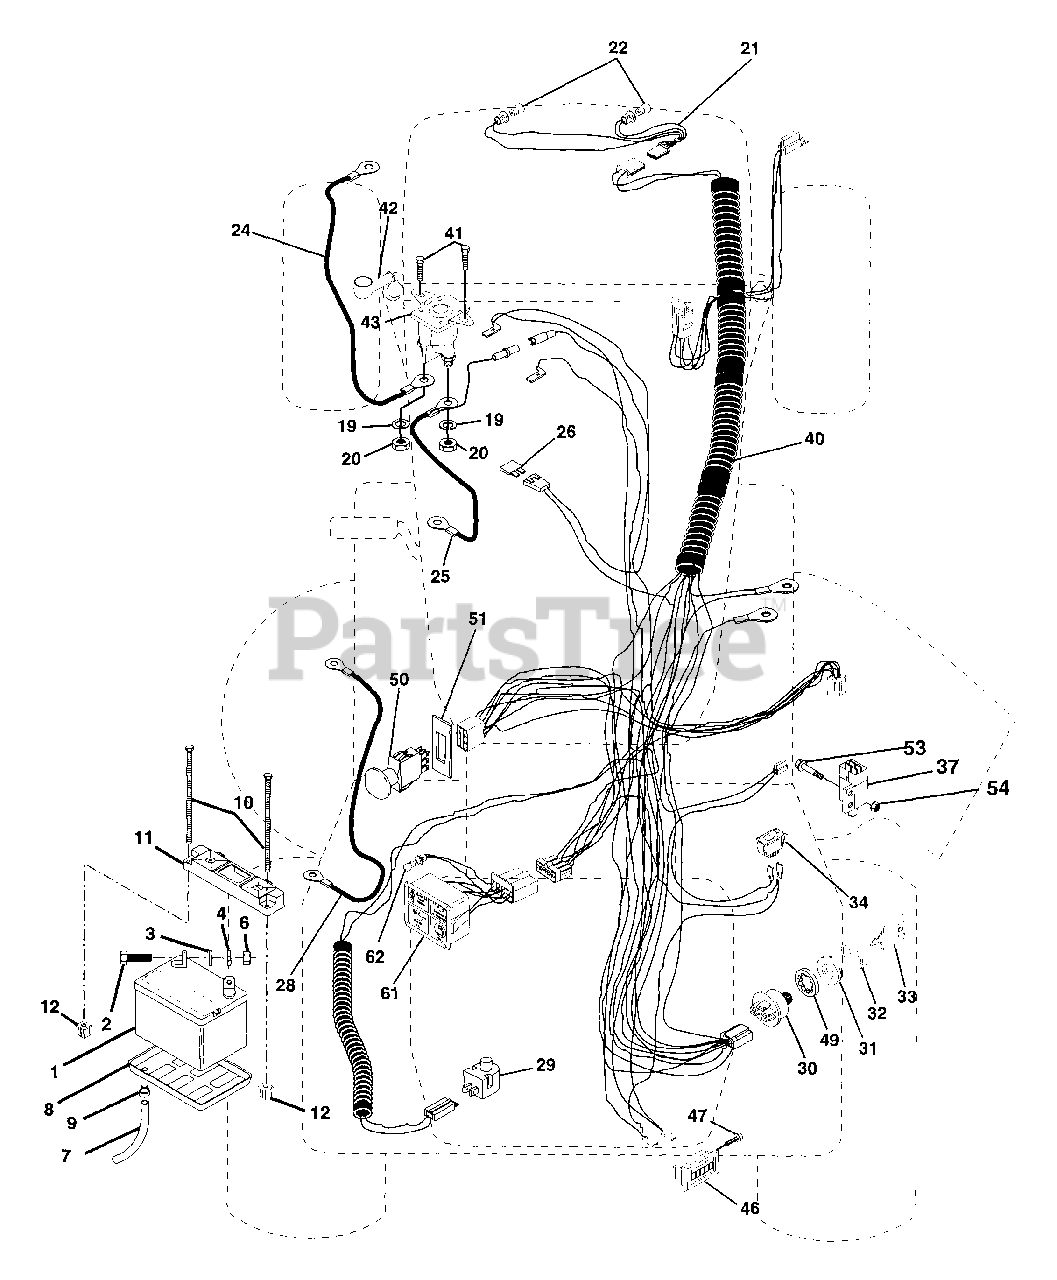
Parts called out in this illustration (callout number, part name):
1	Battery
2	Bolt Hex Head 1/4-20 x 3/4
3	Washer, Lock 1/4
4	Washer 9/32 x 5/8 x 16 Ga
6	Nut Fin Hex 1/4-20
7	Tube, Plastic
8	Tray, Battery
9	Clamp, Hose
10	Bolt, Battery Frt. 1/4-20 x 7-1/2 Zinc
11	Holddown Battery Dash Mount
12	Nut Push Nylon 1/4" Battery Frt.
19	Washer, Lock 1/4
20	Nut, Jam Hex 1/4-20
21	Harness, Socket, Light w/4152
22	Bulb, Light
24	Cable, Starter
25	Cable, Battery Red 4 Ga. w/16 Wire
28	Cable, Ground
29	Switch, Plunger
30	Switch, Ign
31	Nut, Ignition Switch
32	Cover, Switch Key
34	Switch, Light
37	Intlk Switch
40	Harness, Ign.
41	Screw 1/4-20 x 1/2
42	Cover, Terminal Red
43	Solenoid
46	Meter, Hour
47	Screw #10-24 x 1/2
49	Washer, Lock Internal Tooth 5/8
50	Switch, PTO
51	Ring, Retainer, PTO
61	Light Pkg Asm
62	Bulb, Light Pkg.
